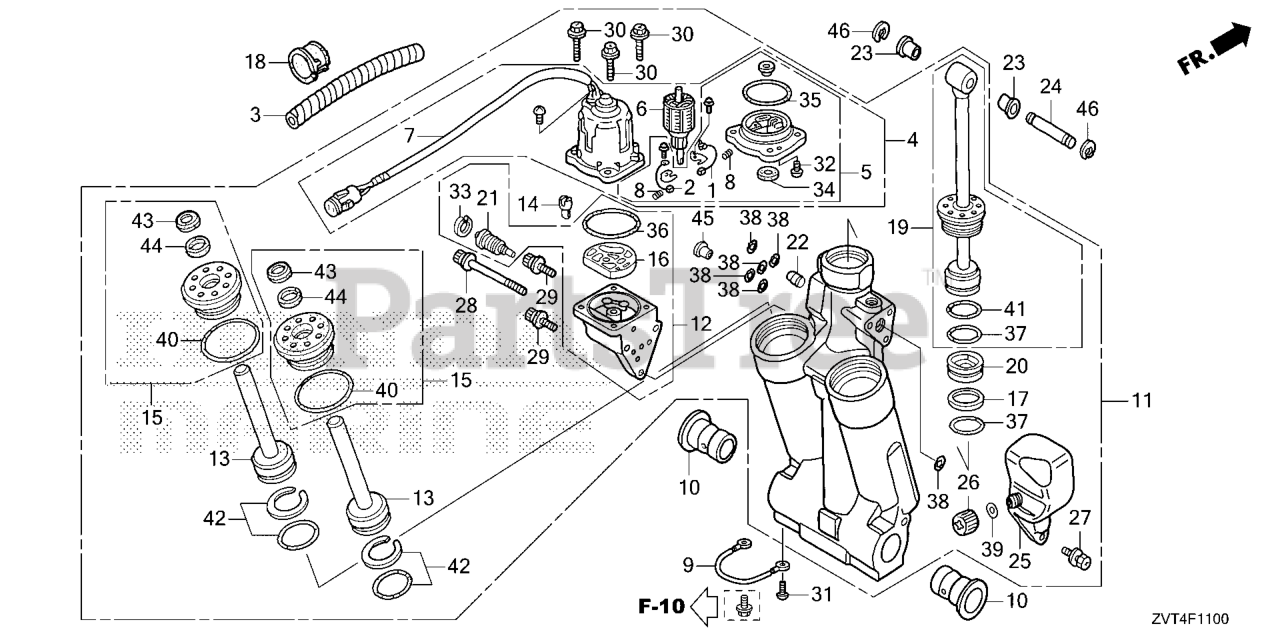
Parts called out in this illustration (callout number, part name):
1	BREAKER ASSY.
2	BRUSH ASSY.
3	TUBE, SPIRAL
4	MOTOR, POWER TILT
5	BRACKET ASSY.
7	YOKE ASSY.
8	SPRING, MOTOR
9	WIRE, LEAD (1.5X116MM)
10	BUSH, SWIVEL CASE
11	TRIM/TILT, POWER
12	PUMP ASSY.
13	ROD, PISTON (B)
14	JOINT, DRIVE
15	GUIDE, ROD
16	FILTER (B)
17	RING, BACK-UP
18	BUSH, MOTOR CODE
19	ROD, PISTON
20	PISTON, FREE
21	VALVE, MANUAL
22	VALVE, RESERVOIR
23	BUSH, CYLINDER (LOWER)
24	PIN, CYLINDER (UPPER)
25	TANK, OIL
26	CAP, OIL TANK
27	BOLT, RECESSED
28	BOLT A, SOCKET
29	BOLT B, SOCKET
30	BOLT, HEX.
31	SCREW, PAN (6X8)
32	SCREW (4X16)
33	CIRCLIP (INNER)
35	O-RING (2.0X70.5)
36	O-RING (1.8X69.6)
37	O-RING (3.5X38.7)
38	O-RING (1.68X7.25)
39	O-RING (1.9X11)
40	O-RING (3.5X35.7)
41	O-RING (3.5X41.7)
42	O-RING SET (3.5X31.7)
43	SEAL, WATER
45	COLLAR, ORIFICE
46	E-RING (15MM)
